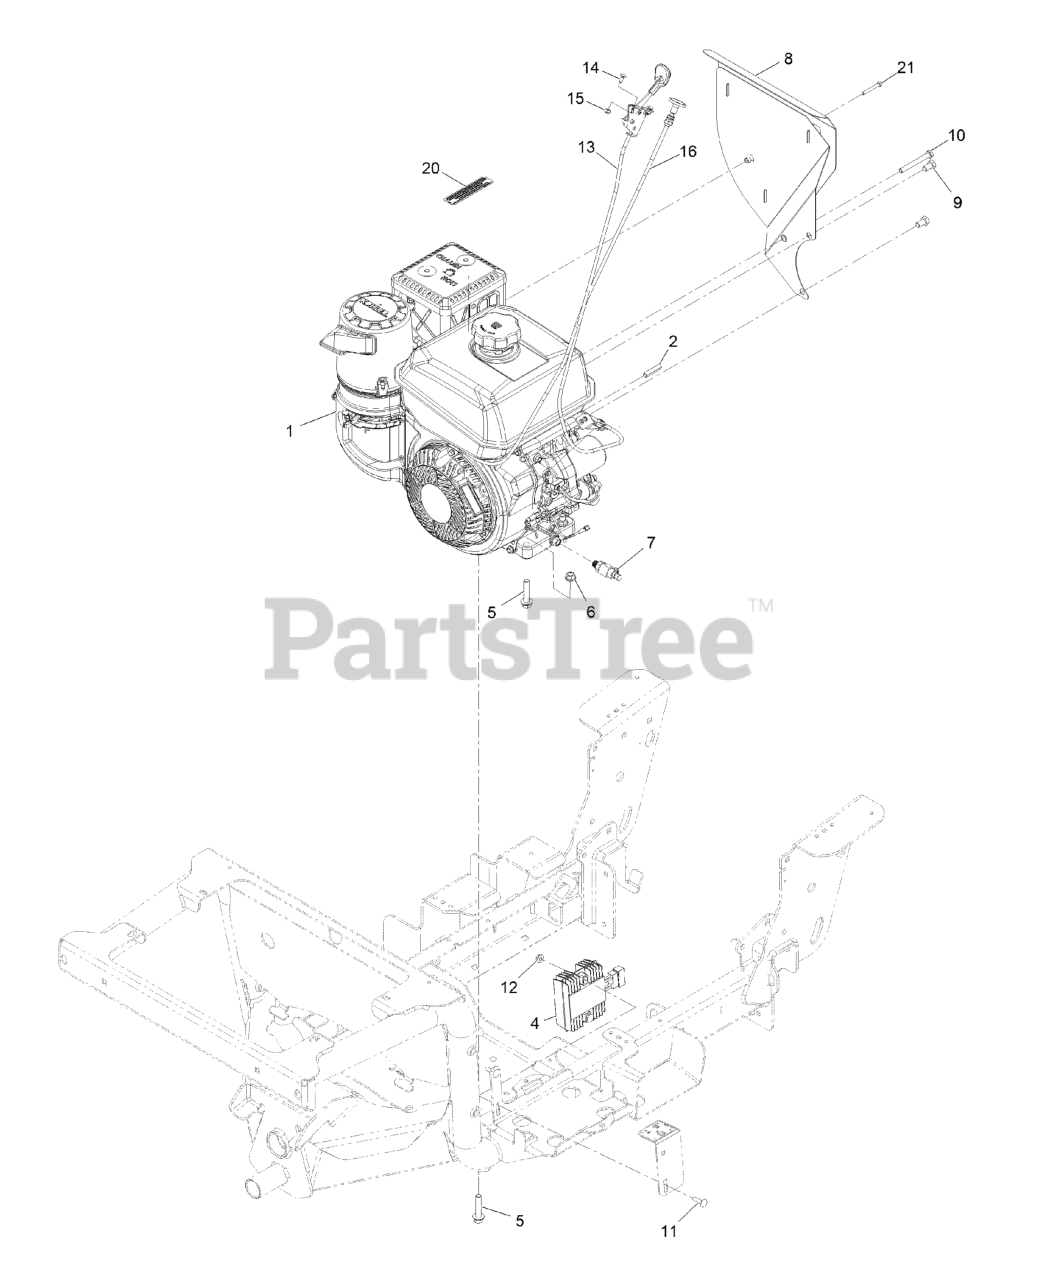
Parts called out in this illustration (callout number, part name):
1	Engine-Kohler, Ch395
2	KEY-SQUARE, 7MM
4	REGULATOR-TROMBETTA, 18A
5	SCREW-HHF
7	Valve-Drain, Oil
8	HEAT SHIELD ASM
9	Screw-HH
10	Screw-HH
11	Screw-CARR
13	Control-Throttle
14	BOLT-CARR
15	NUT-LOCK, NI
16	Cable-Choke, Push/Pull
20	DECAL-ARRESTOR, SPARK
21	BOLT-M5X0.8MM X 40 MM LON
